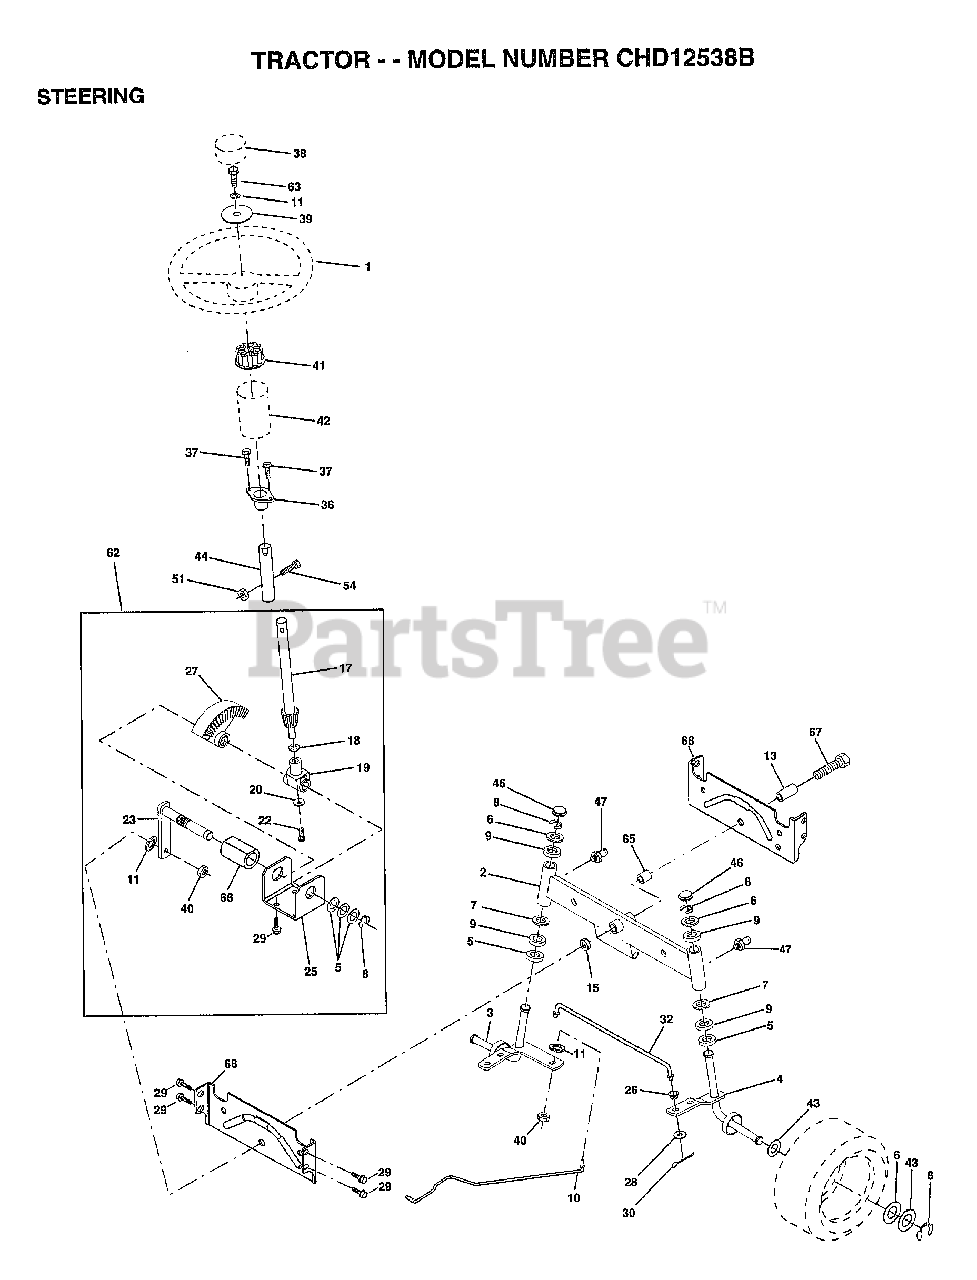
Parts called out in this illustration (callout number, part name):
1	WHEEL STR AYP BLK
2	AXLE ASM
3	SPINDLE.ASM.LH
4	"SPINDLE ASM,RH"
5	WASHER .T
6	WASHER
7	WASHER
8	RING
9	COL. SRTG. BEAR.
10	DRAGLINK-STAMPED
11	LOCKWASHER
13	BEARING AXLE
15	"NUT-LOC,FLANGE LT"
17	SHAFT ASM STEERIN
18	THRUST WASHER
19	SUPPORT.SHAFT
22	SCREW HEX SOC1/4-
25	BRKT-STEERING
26	BUSHING.DRAGLINK
27	GEAR SECTOR
28	WASHER
29	SCREW
30	COTTER PIN
32	TIE ROD
36	BUSHING.STEERING
37	"SCREW-TT,10-32 FL"
38	CAP STEER AYP
39	WASHER T
40	GRIPCO NUT
41	ADAPTER LT
42	BOOT.STEER.PL
44	EXT SHAFT STEERIN
46	CAP
47	ZERK M
51	NUT
54	BOLT
62	KIT STEERING ASM
63	BOLT
65	SPACER AXLE
66	"BEARING-ARM,PITMA"
67	BOLT
68	BRACE AXLE
